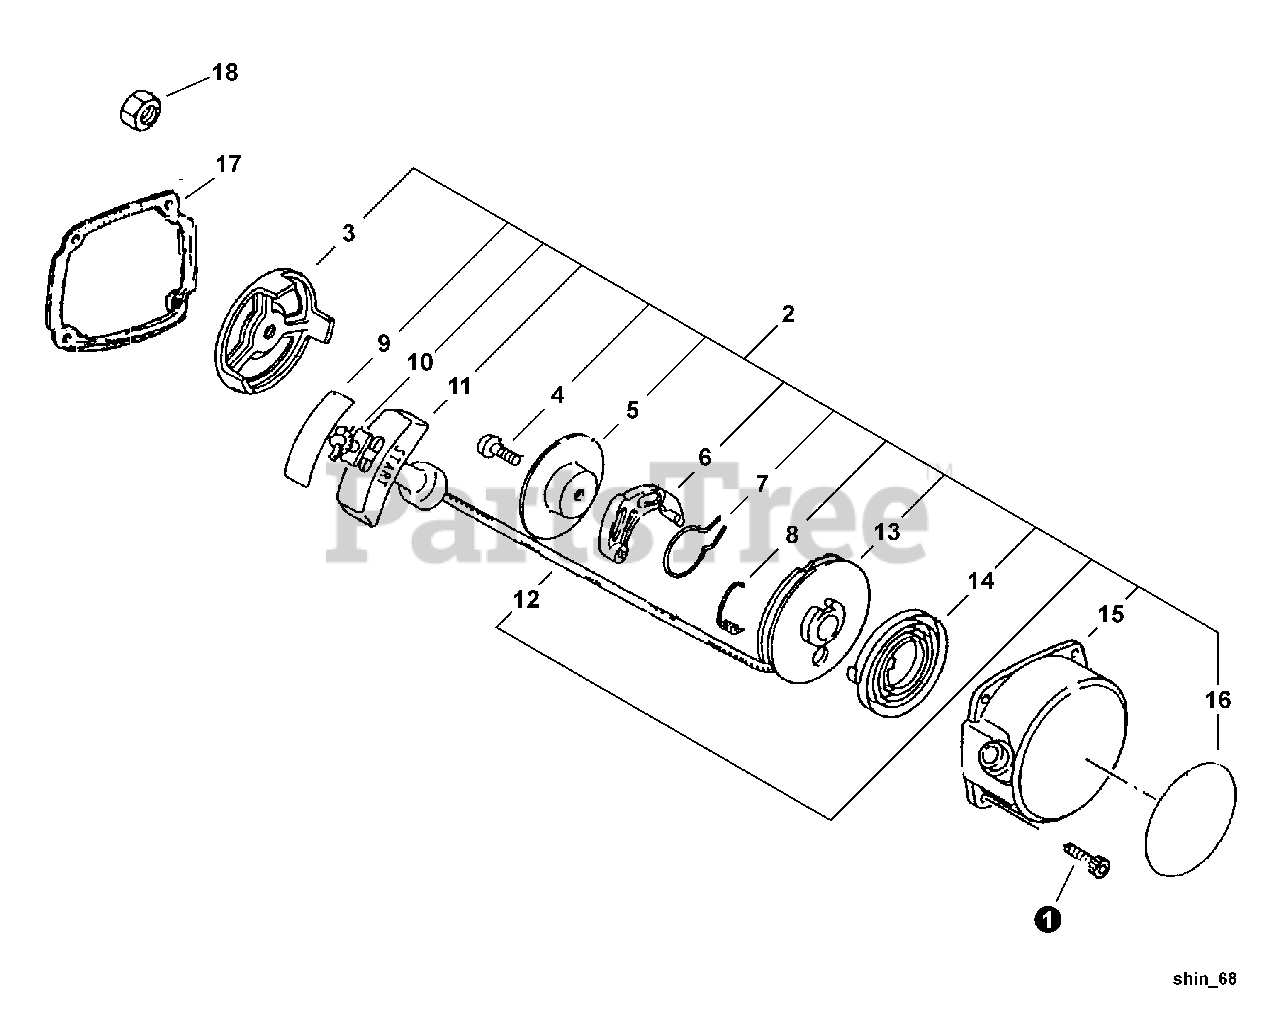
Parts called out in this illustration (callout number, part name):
1	SCREW - 4X16
2	STARTER ASSY
3	CATCHER, STARTER
4	SCREW
5	PLATE, STARTER
6	PAWL, STARTER
7	SPRING
8	SPRING, RETURN
9	TAPE
10	RETAINER, ROPE
11	GRIP, STARTER
12	ROPE
13	REEL, ROPE
14	SPRING, REWIND
15	CASE, STARTER
17	GASKET
18	NUT - 8
